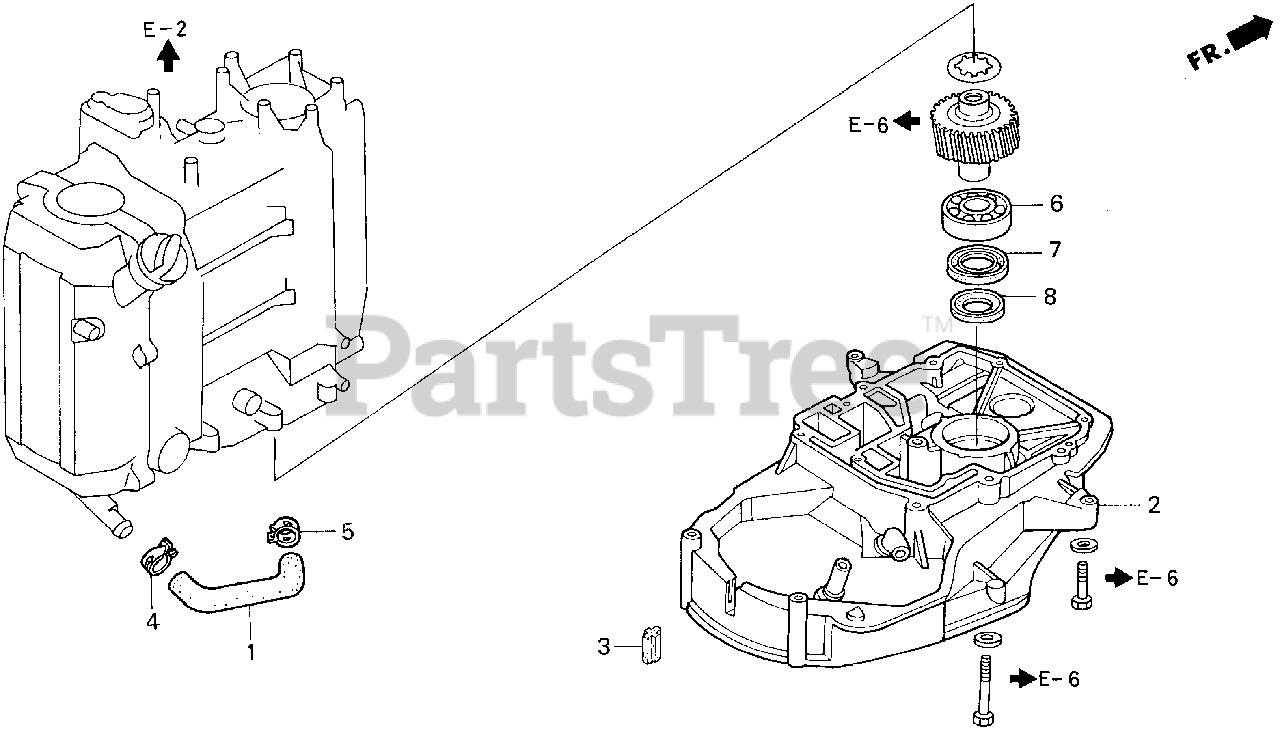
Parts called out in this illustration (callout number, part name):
1	TUBE, OIL
2	CASE, PRIMARY GEAR *NH8* (DARK GRAY)
3	RUBBER, SEAL
4	CLAMP, TUBE (D22)
5	CLAMP, TUBE (D18.8)
6	BEARING, RADIAL BALL (6205)
7	OIL SEAL (25X40X7)
8	SEAL, WATER (17X26X7)
